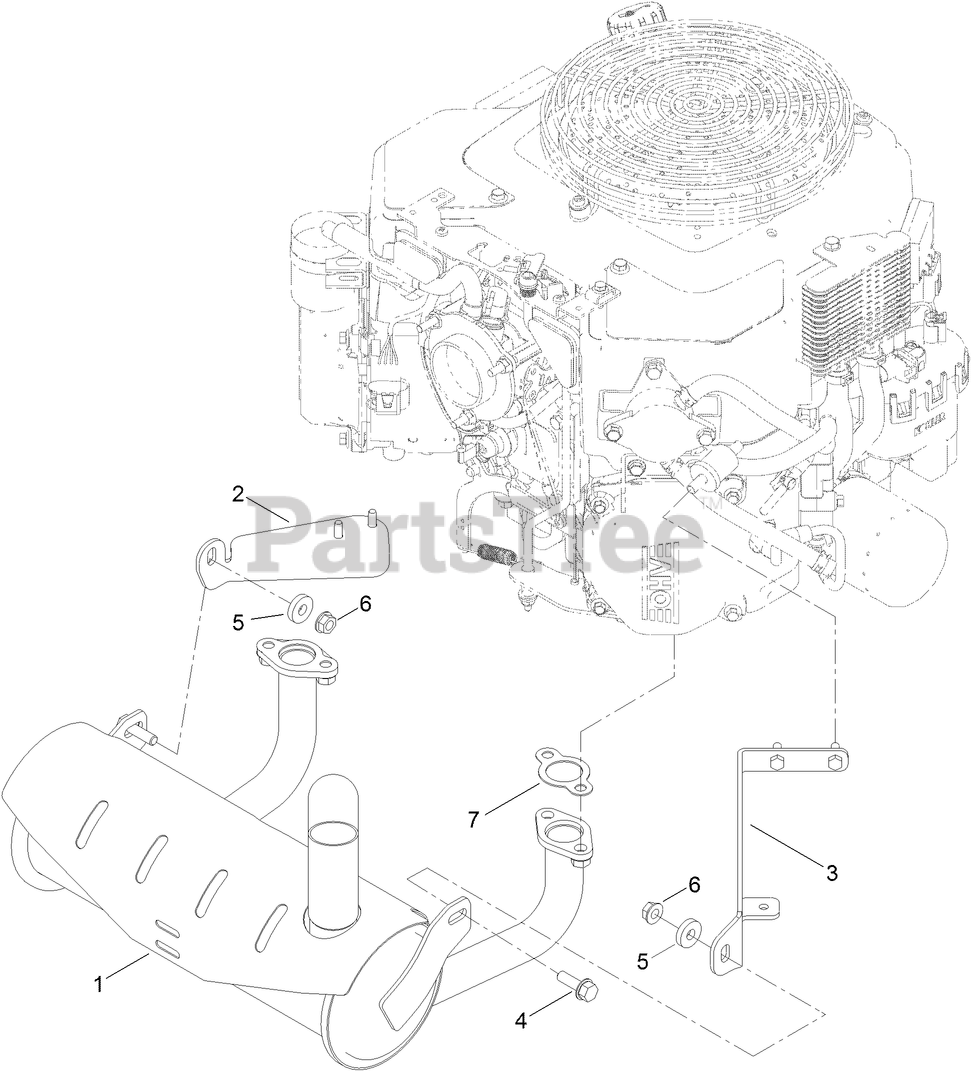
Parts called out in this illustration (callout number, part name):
1	MUFFLER
2	BRACKET-MUFFLER, RH
3	BRACKET-MUFFLER, LH
4	SCREW-HHF
5	SPACER
6	NUT-HF
7	GASKET-EXHAUST
